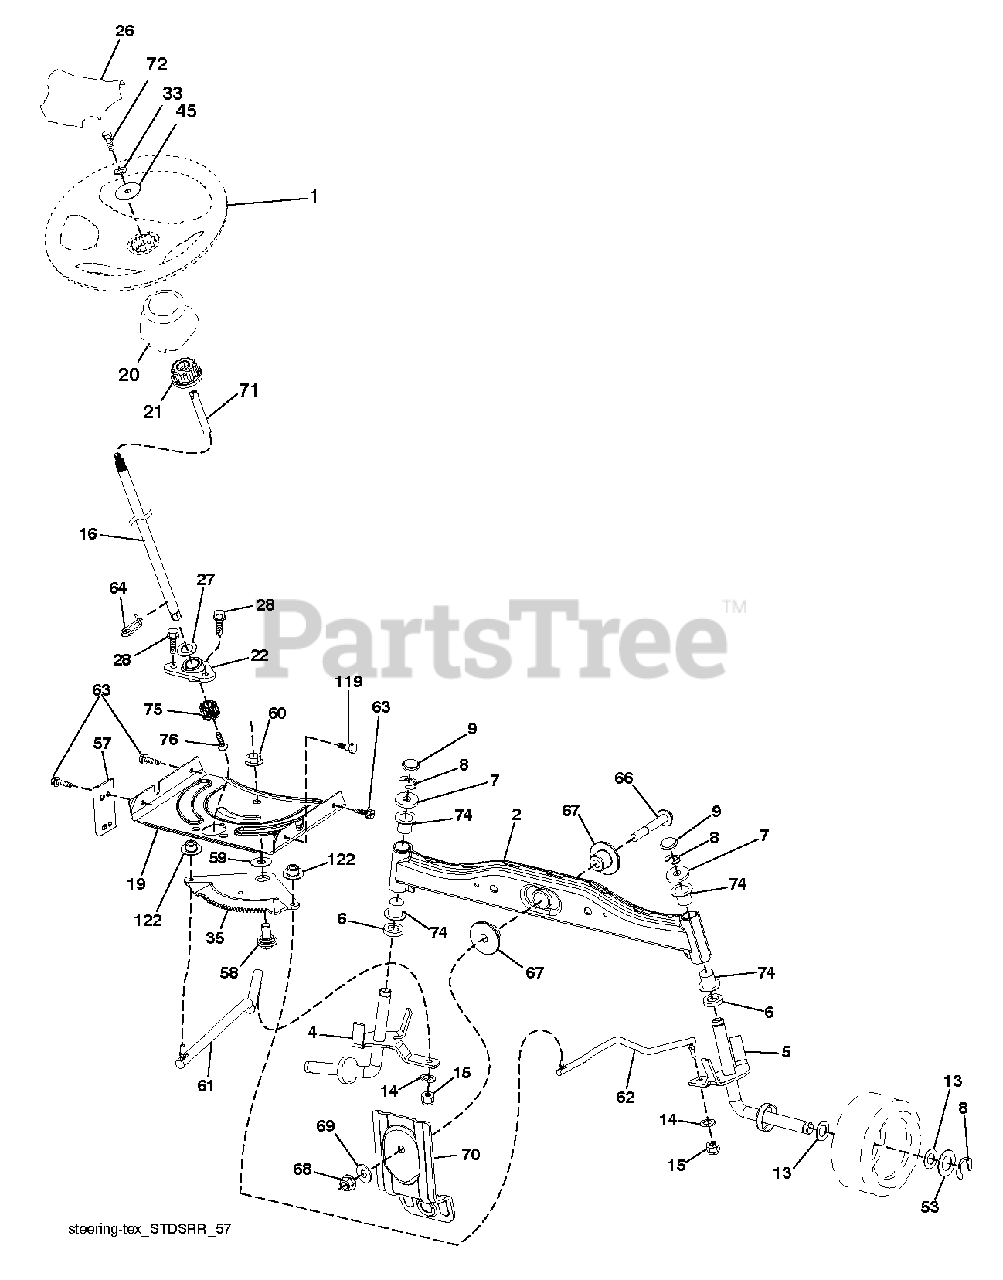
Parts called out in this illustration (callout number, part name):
1	WHEEL.STEERING.STDSRR.BLK/OV
2	AXLE HALF ASM-WELDED
8	RING CLIP
9	CAP.SPINDLE
14	WASHER, LOCK 3/8
15	NUT CROWNLOCK 3/8-24
16	Steering Shaft Service Kit, .3Hi Shaft
19	PLATE.STEER.DDL.NLT/NG
20	BOOT.STEERING.PREDATOR.LT.BLAC
21	ADAPTER, WHEEL STNG..
22	Steering Shaft Service Kit
26	CAP.WHL.STRNG.STDSRRD.SRS.BLK
27	WASHER LT
28	SCREW, 3/8-16X3/4
33	LOCKWASHER
35	GEAR.SECTOR.PLATE.DDL.
45	WASHER.11/32
53	WASHER.HARDENED
57	BRACKET.UPSTOP.TEX
58	BOLT.SHOULDER.SECTOR.P
59	WASHER.THURST.SECTOR.S
60	NUT FLANGE LOCK 5/8-11
61	DRAGLINK.LH.BALLSTUD.D
62	DRAGLINK.RH.BALLSTUD.D
63	SCREW
64	RETAINER.CLIP.SPRING.S
66	BOLT HEX FGHD 7/16-14 X 3 SERR
67	BUSHING.PM.FRONT AXLE
68	NUT.LOCK.FLANGE.7/16
69	WASHER.1.5X.505X.118
71	SHAFT.EXTEN.STRG.SPLINE
72	BOLT 5/16-18 X 4 W/PATCH
74	BRNG T
75	Steering Shaft Pinion Kit
76	Screw Head Socket Lrvb
119	SHOULDER BOLT 5/16-18TT
